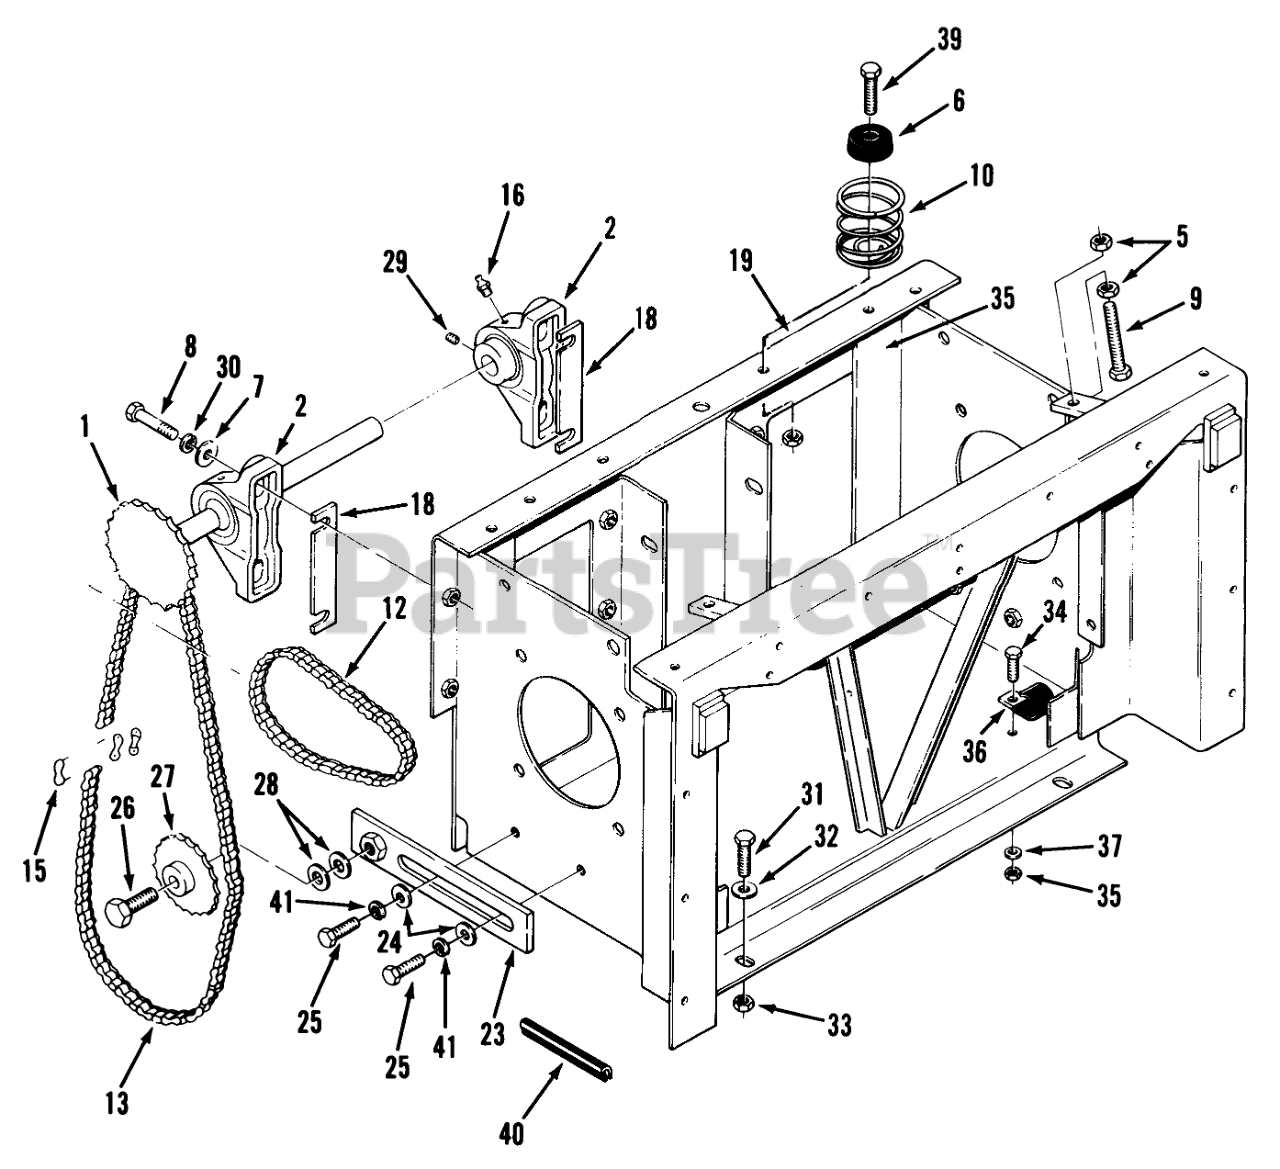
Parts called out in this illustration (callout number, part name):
1	ASSY-JACKSHAFT PLT
2	Pillow Block Bearing (Includes items 16 & 29)
5	Nut
6	BUMPER
7	Bolt
8	BOLT
9	Hex Hd. Mach. Screw 5/16-18 x 2-1/4
10	SPRING
12	CHAIN-#50 PRIMARY
13	ROLLER-CHAIN #50 SEC
15	CONNECTING LINK
16	Fitting-Grease
18	SHIM-PILLOW BLOCK
19	Transaxle Frame
23	ASSY-CHAIN TENSIO B
24	Washer
25	BOLT
26	HEX HD CAP SCREW
27	IDLER SPROCKET 20288
28	WASHER
29	SCREW-SET
30	LOCKWASHER
31	BOLT
32	Washer
33	NUT
34	Bolt
35	Nut
36	CLIP
37	WASHER 5/16 SAE
39	Bolt
40	EDGE TRIM
41	LOCKWASHER
